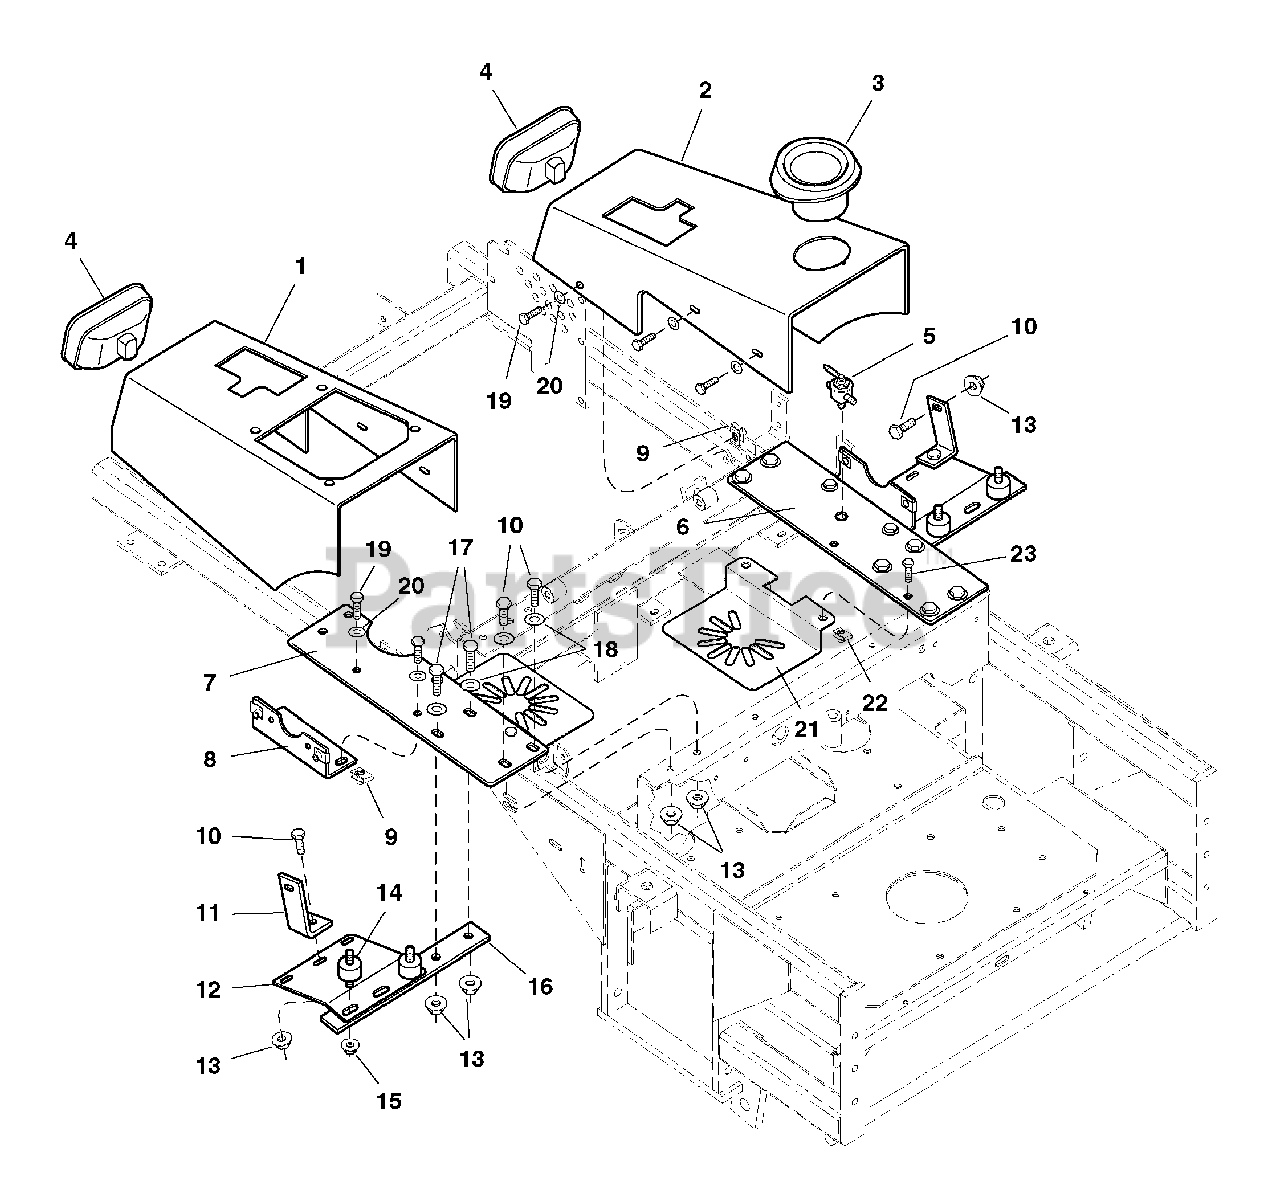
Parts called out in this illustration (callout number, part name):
1	CONTROL COVER-LH
2	CONTROL COVER-RH
4	HEADLIGHT ASSEMBLY, Complete
5	VALVE, Fuel Shut Off
6	COVER MOUNT-RH
7	COVER MOUNT-LH
8	BRACKET, Cover Mount
9	BODY CLIP, 5/16-18
10	CAPSCREW, Hex Hd, 3/8-16 x 3/4
11	BRACKET, Cover Support
12	DEBRIS GUARD
13	NUT, Hex, Serrated Flange, 3/8-16
14	RUBBER ISOLATOR
15	NUT, Hex, Serrated Flange, 5/16-18
16	TANK MOUNT BAR
17	CAPSCREW, Hex Hd, 3/8-16 x 1
18	WASHER, 3/8
19	CAPSCREW, Hex Hd, 5/16-18 x 1
20	WASHER, 5/16
21	FAN SHIELD
22	BODY CLIP, 1/4-20
23	BOLT, 1/4-20 X 1", GD
